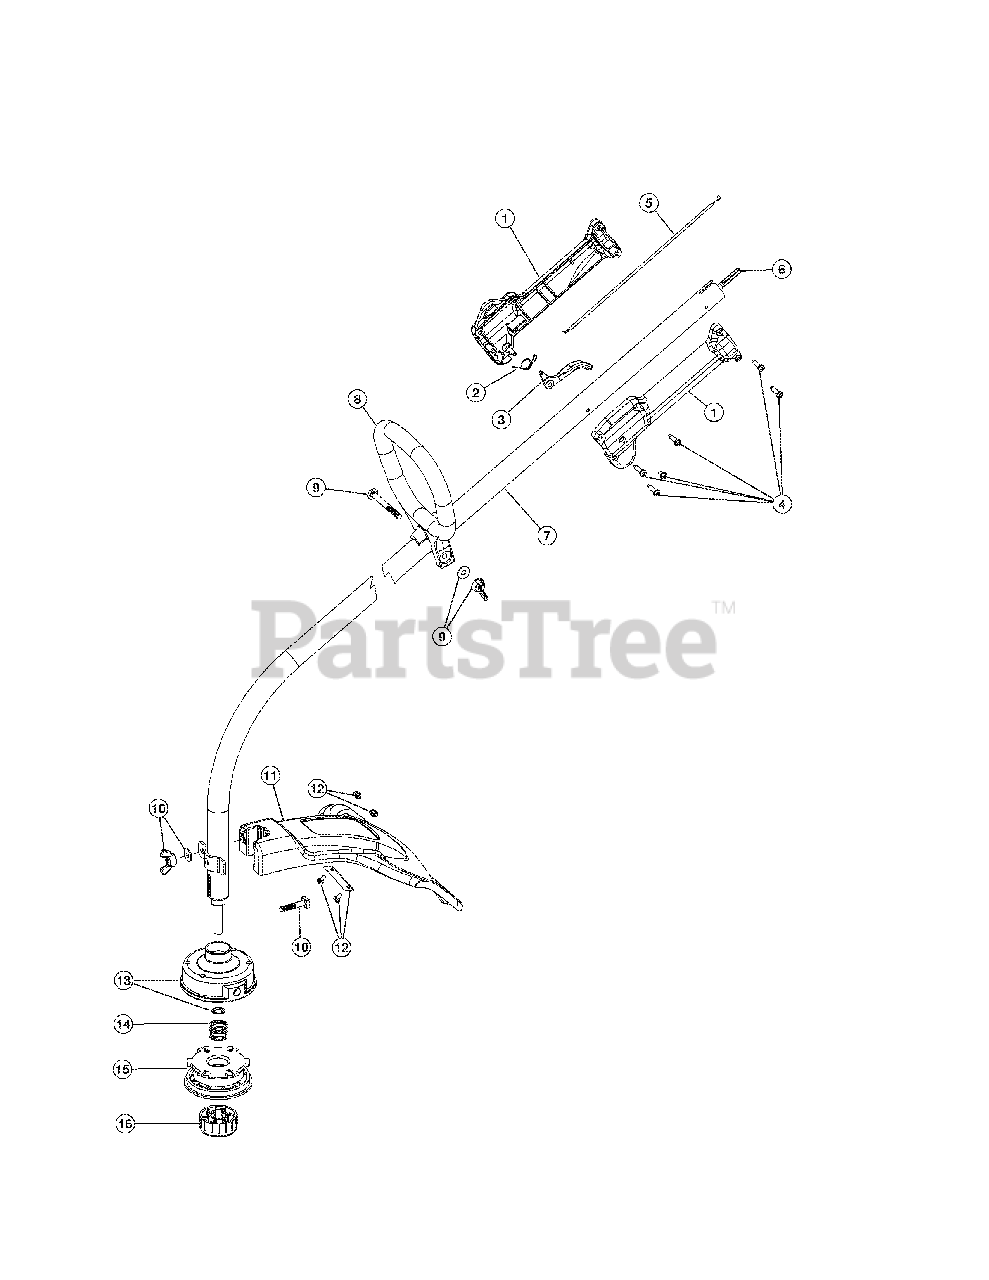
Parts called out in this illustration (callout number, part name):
1	Throttle Housing and Trigger Assembly (includes 2-4)
2	Throttle Trigger Spring
3	Throttle Trigger
4	Throttle Housing Screws
5	Throttle Cable
6	Flexible Drive Shaft
7	Drive Shaft Housing
8	D-Handle Assembly (includes 9)
9	D-Handle Hardware
10	Guard Mounting Hardware
12	Blade Assembly
13	Outer Reel w/Retainer
15	Inner Reel
16	Bump Knob
